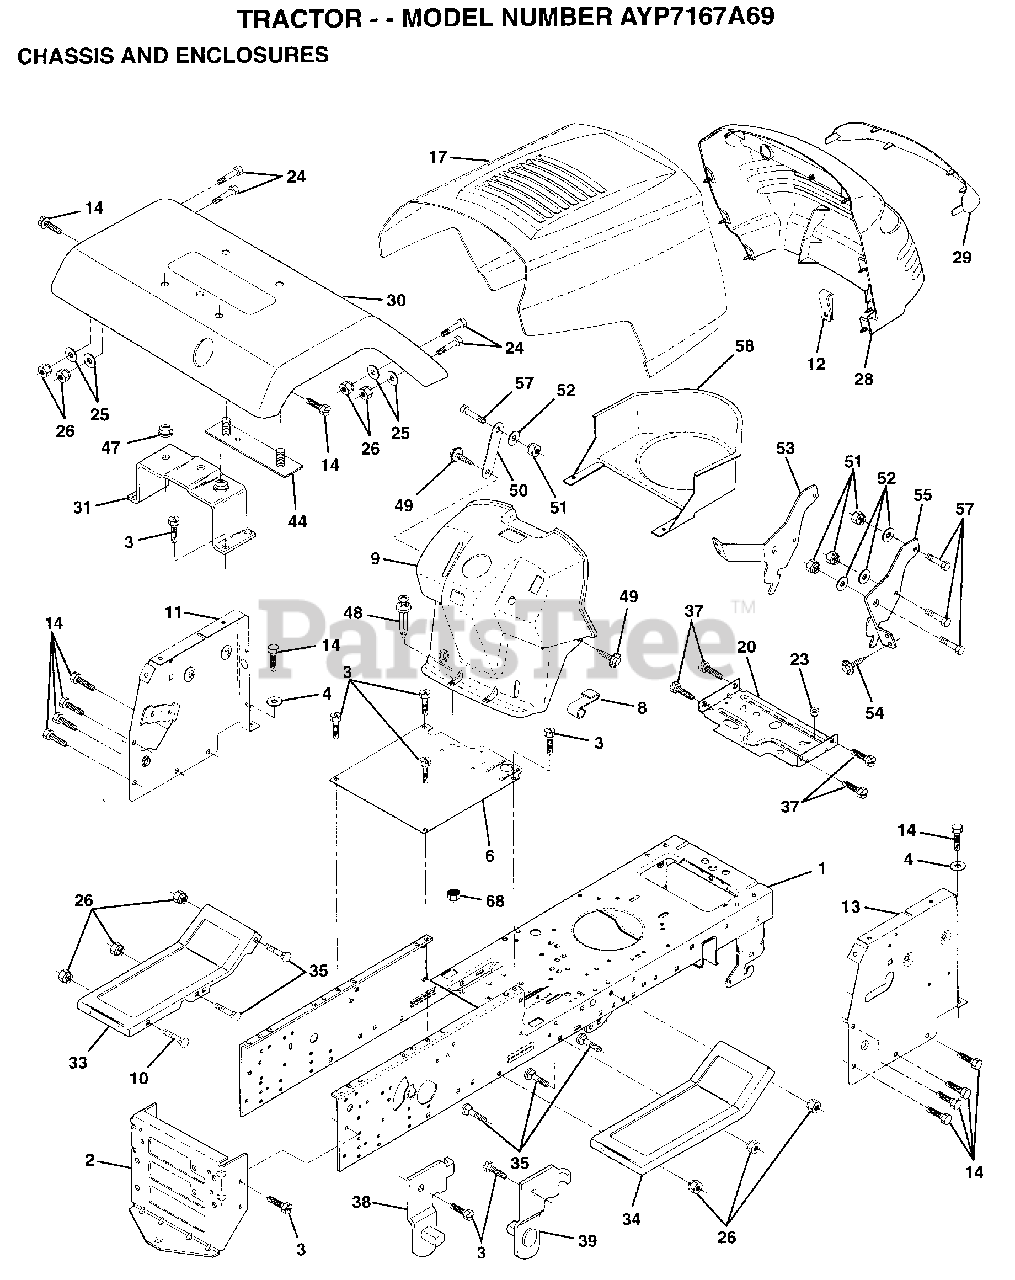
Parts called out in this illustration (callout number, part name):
1	CHASSIS.WLD.11GA
3	SCREW
4	WASHER
8	"CLIP,INSULATOR"
11	PANEL ASM DASH
12	CLIP.TINNERMAN
14	SCREW LT
17	HOOD.STL.PRV.LB
20	PLATE.MTG.BTRY.TK
24	BOLT
25	WASHER
26	NUT
29	LENS GRILLE
31	BRKT.ASM.FENDER
33	FOOTREST.LT.LT/GT
34	FOOTREST.RH.LT/GT
35	BOLT
37	SCREW TI
38	BRACKET ASM LH
39	BRACKET ASM RH
44	STRAP ASM FENDER
47	NUT-PUSH YT
48	RIVET.PUSH.PLATE
49	SCREW HEX CRT
50	BRACE SUPT DASH
51	NUT
52	WASHER
53	BRACKET.GRILLE.LH
55	BRACKET.GRILLE.RH
58	DUCT AIR 12-15H
68	NUT
